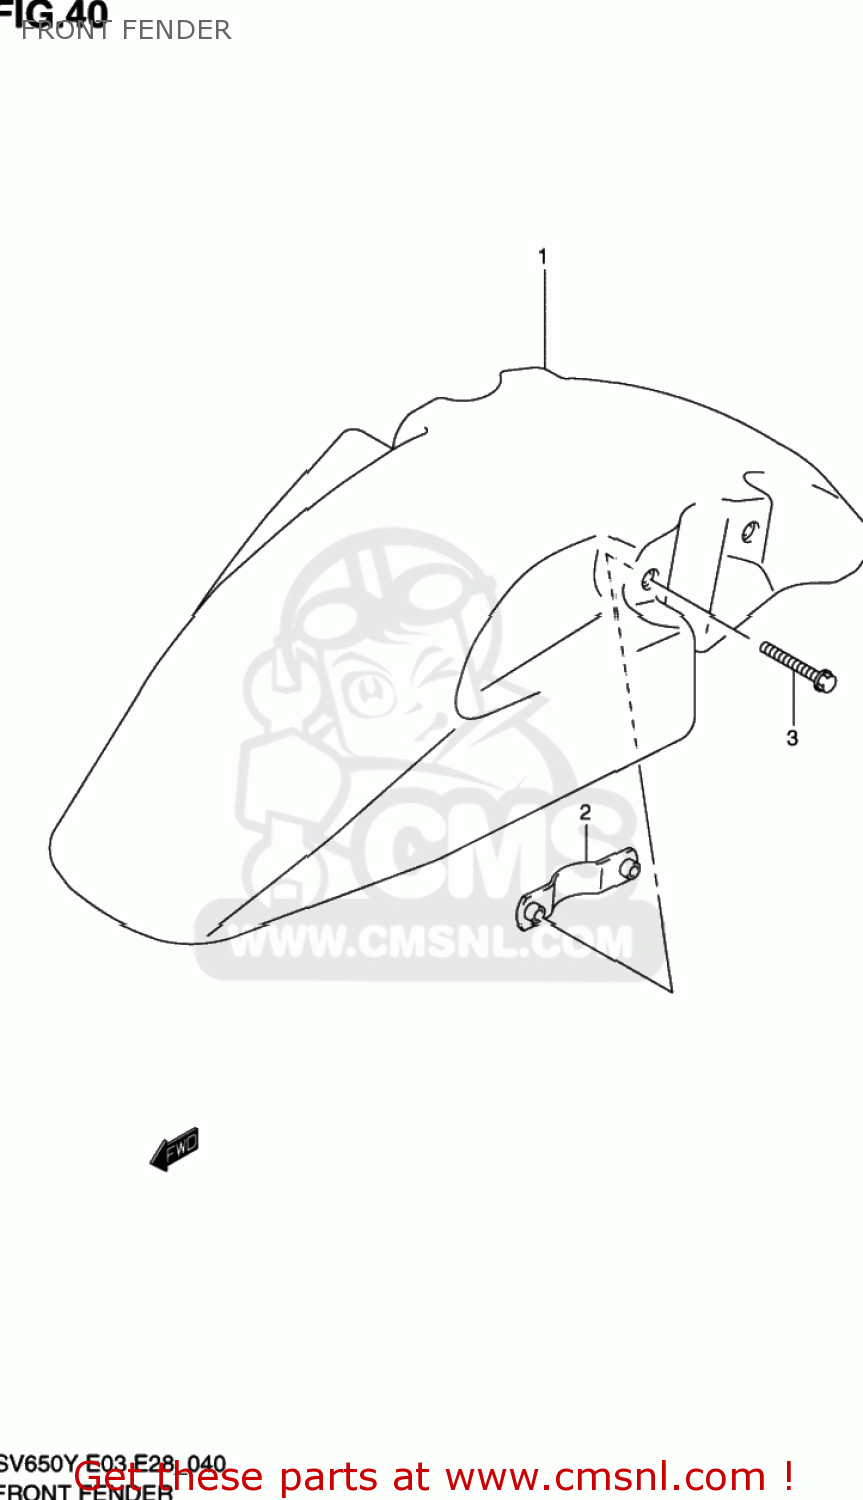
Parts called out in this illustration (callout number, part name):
1	FENDER SET,FR
2	PLATE,FR FENDER
3	BOLT
